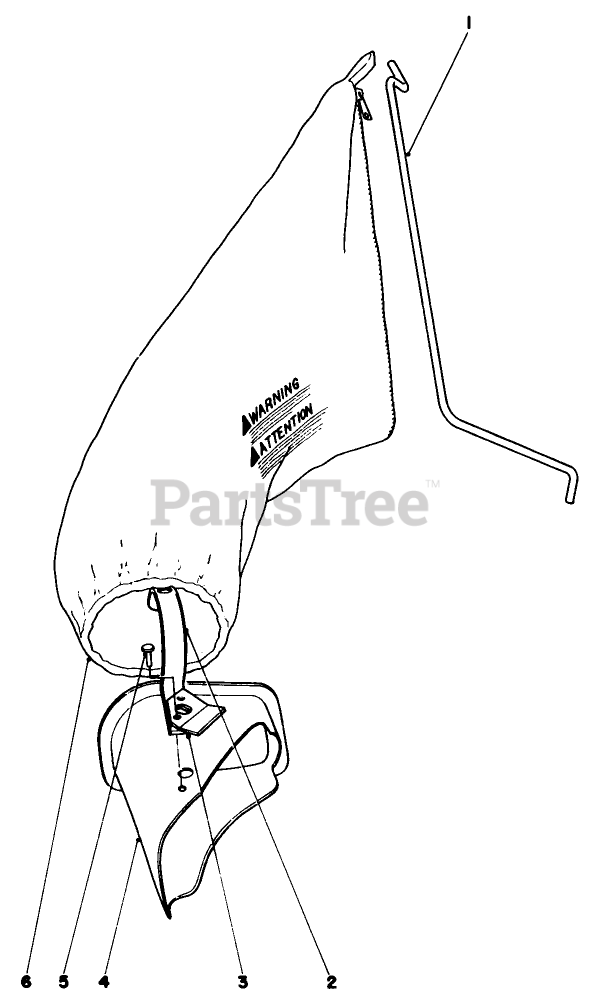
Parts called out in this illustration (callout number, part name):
1	BAG HANGER ROD
2	Handle Bag Chute
3	Stop Deflector
4	Grass Chute (Incl. Ref. #2 & 5)
5	Rivet Semi Tubular
6	BAG REPLACMNT44-0540
